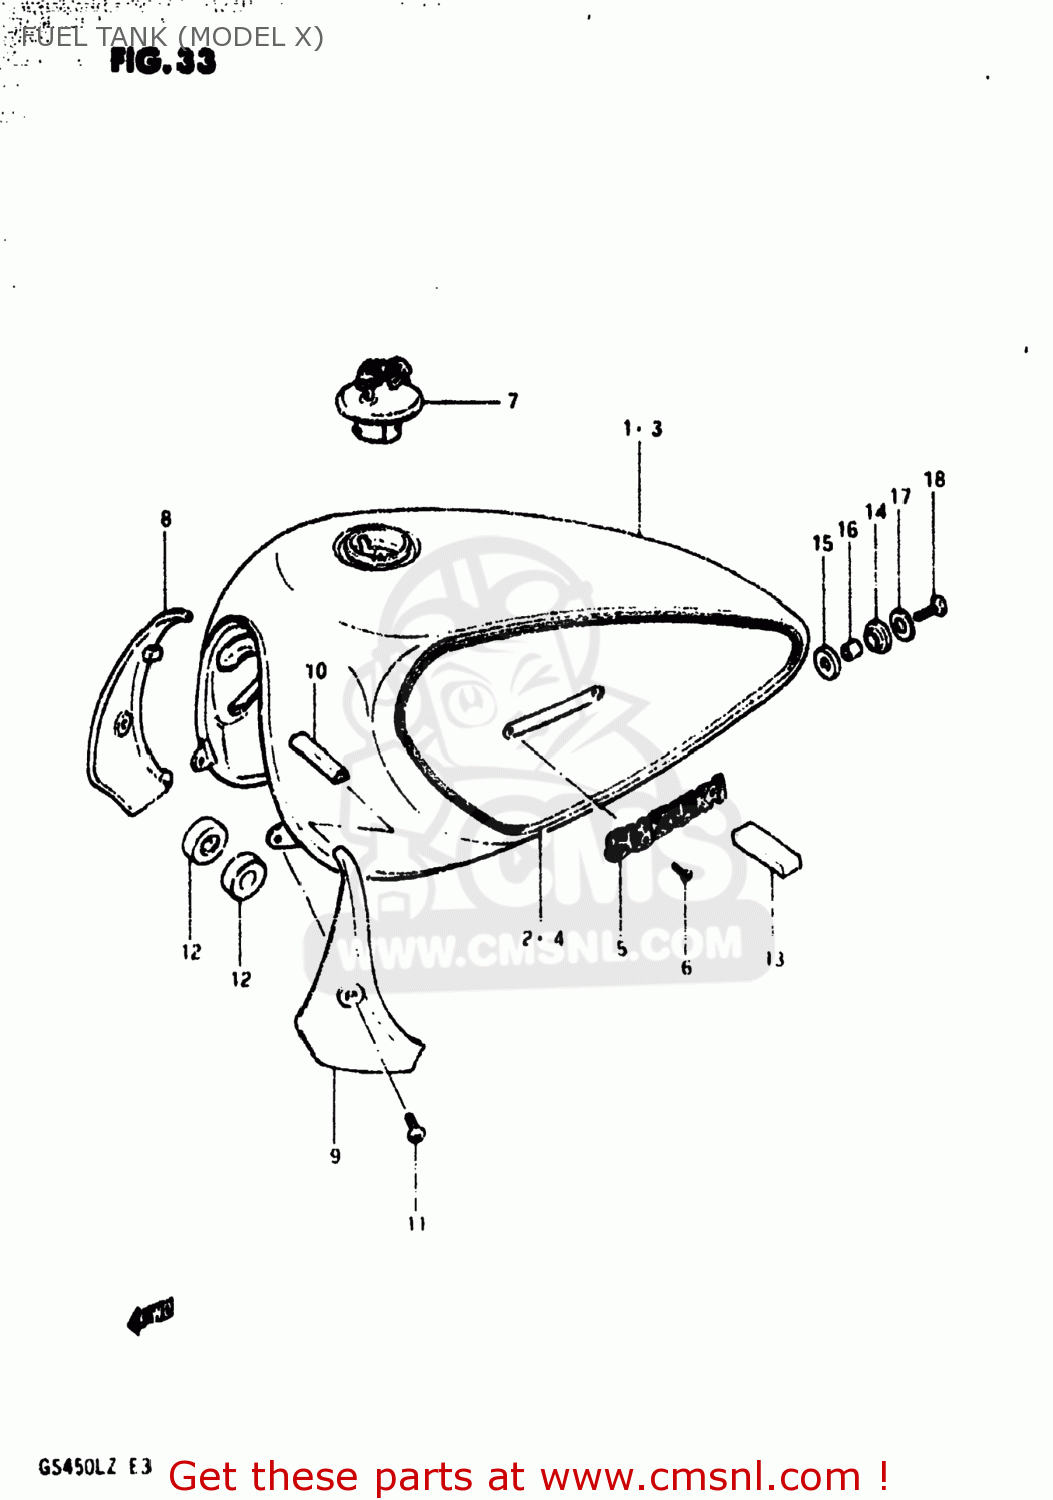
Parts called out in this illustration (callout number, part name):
1	TANK ASSEMBLY,FUEL
2	TAPE SET,FUEL TANK
3	TANK ASSEMBLY,FUEL
4	TAPE SET,FUEL TANK
5	EMBLEM,FUEL TANK
6	SCREW 3X6
7	CAP SET,FUEL TANK
8	COVER,FUEL TANK,FRONT,RIGHT
9	COVER,FUEL TANK,FRONT,LEFT
10	TUBE, FRONT
11	SCREW 6X12
12	CUSHION
13	CUSHION
14	CUSHION
15	CUSHION
16	SPACER(8.5X12X19)
17	WASHER (8.5X29X1.6)
18	BOLT (8X30)
